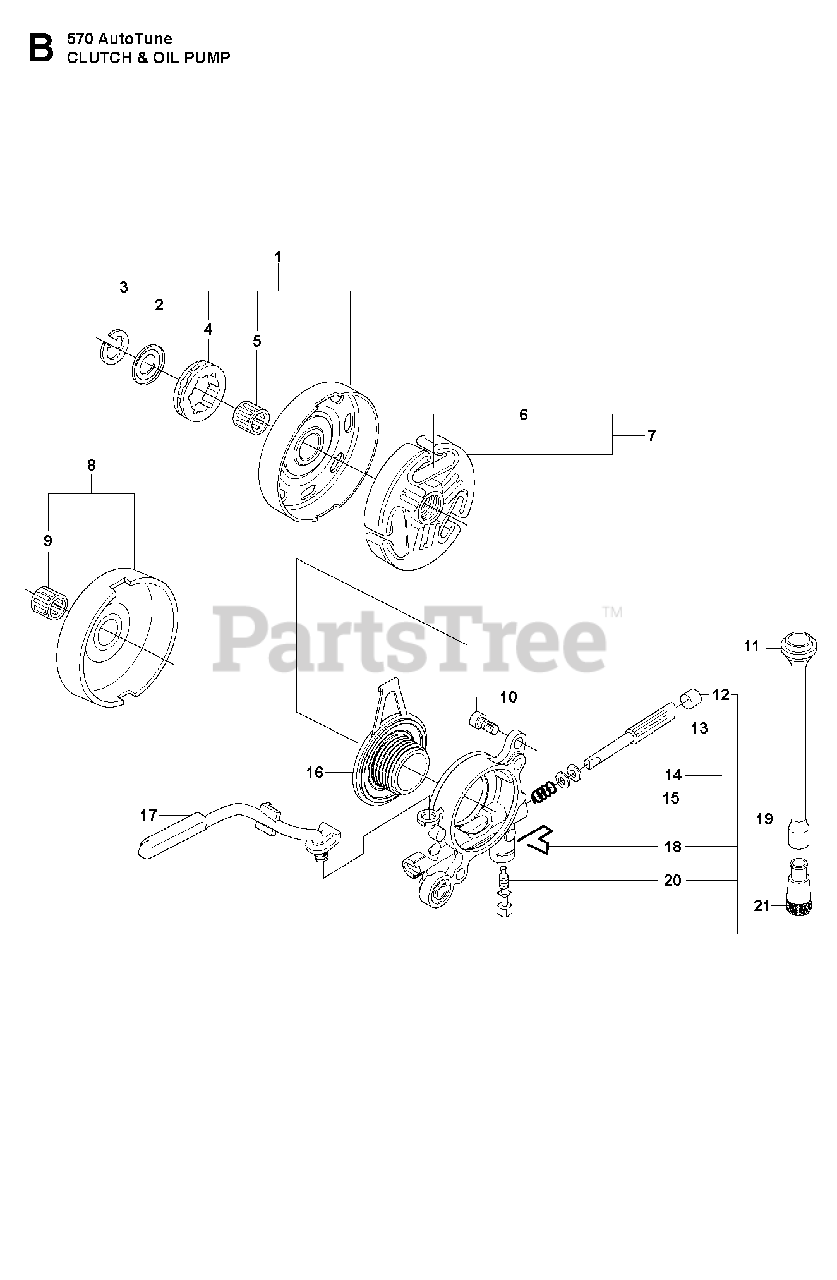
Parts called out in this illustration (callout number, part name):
1	CLUTCH DRUM ASSY
3	RETAINING RING
4	68210 RIMSPROCKET
4	Power Mate Rim
5	CLUTCH DRUM BEARING
6	SPRING
7	CLUTCH
8	CLUTCH DRUM
9	CLUTCH DRUM BEARING
12	PLUG
13	PUMP PISTON
14	WASHER 6.1X9
15	SPRING
16	PINION
18	SPRING CLIP
19	OIL PUMP
20	SCREW
21	OIL SCREEN
